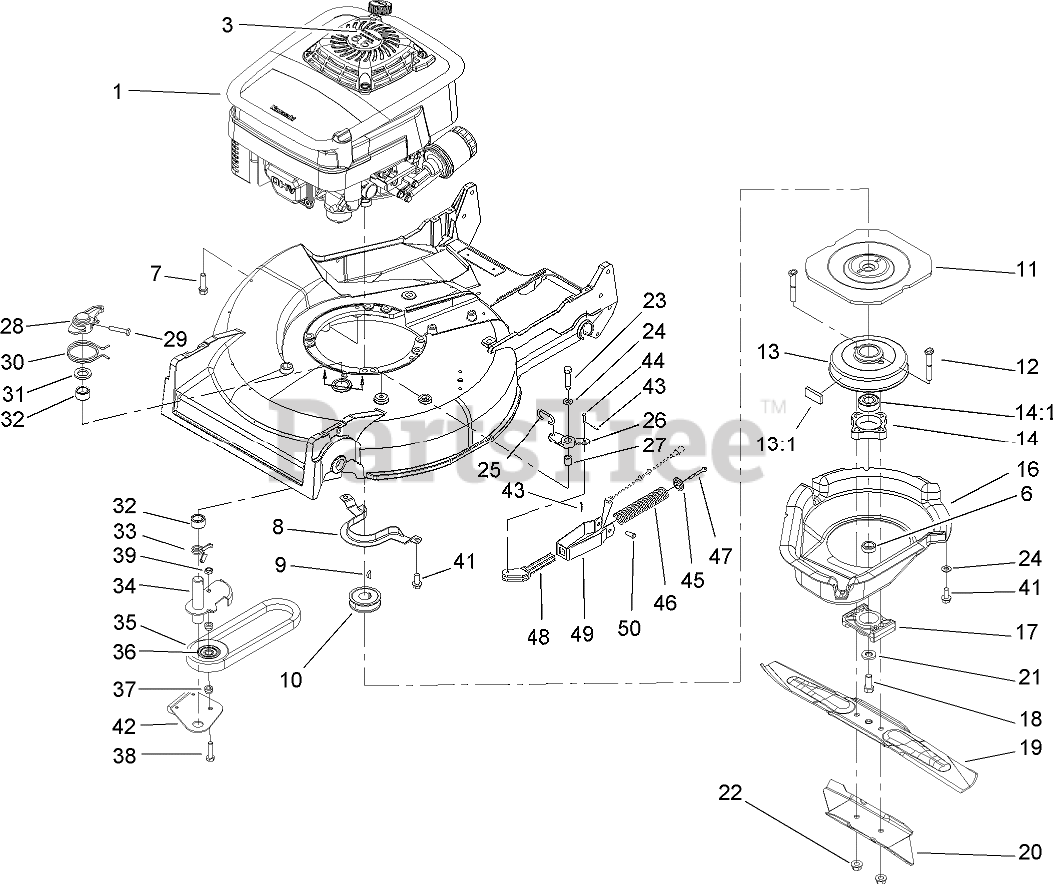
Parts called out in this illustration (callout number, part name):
1	Engine ASM
3	DECAL-RECOIL
6	SPACER-SHAFT, OUTPUT
7	SCREW-TAPTITE
8	BRACKET-GUIDE, BELT
9	KEY-WOODRUFF
10	PULLEY-DRIVER
11	FLYWHEEL-BBC
12	BOLT-BLADE
13	BRAKE DRUM ASM
13:1	DAMPENER-VIBRATION
14	HUB ASM
14:1	BEARING-BALL
16	SHIELD
17	SPACER-BLADE
18	SCREW-HH
19	BLADE-21 INCH
20	STIFFENER-BLADE
21	CAP-ENGINE
22	NUT-LOCK
23	SCREW-HH
24	WASHER-PLAIN
25	LINK-CONTROL
26	BELLCRANK
27	SLEEVE-BELLCRANK
28	LEVER
29	SCREW-HH
30	SPRING-TORSION
31	WASHER
32	BEARING
33	SPRING-TORSION
34	ARM-IDLER
35	V-BELT
36	PULLEY-IDLER
37	SPACER-PULLEY, IDLER
38	SCREW-HH
39	NUT-LOCK, NI
41	SCREW-HWHTF
42	BRAKE PLATE ASM
43	PIN-COTTER
44	PIN-SPRING
45	RETAINER-SPRING
46	SPRING
47	SCREW-HWHTF
48	GUIDE-SPRING
49	BRACKET-SPRING
50	PIN-CABLE
